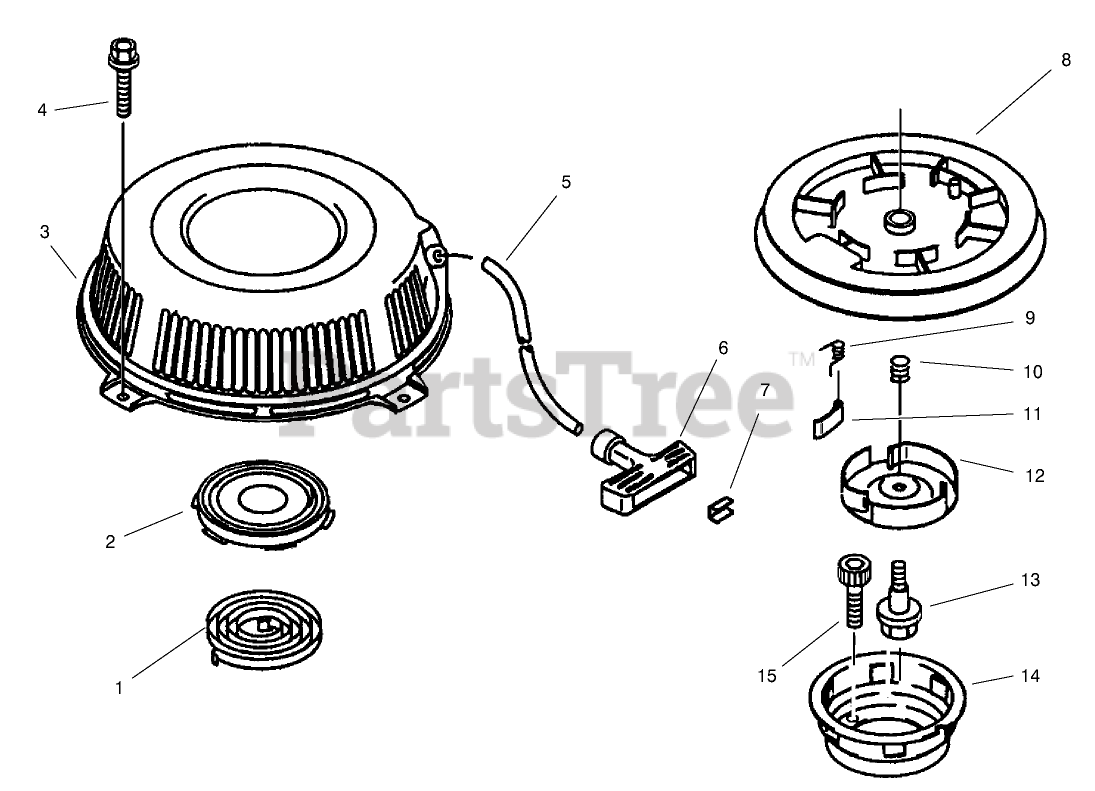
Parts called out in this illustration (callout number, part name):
1	Spring-Recoil
2	Case
3	Case-Recoil Starter
4	BOLT-FLANGED (6X10)
5	Rope
6	Grip
7	Washer
8	Reel
9	Spring
10	Spring
11	Pawl
12	Retainer
13	Bolt
14	Pulley-Starting
15	Bolt-Socket
16	Starter-Recoil
